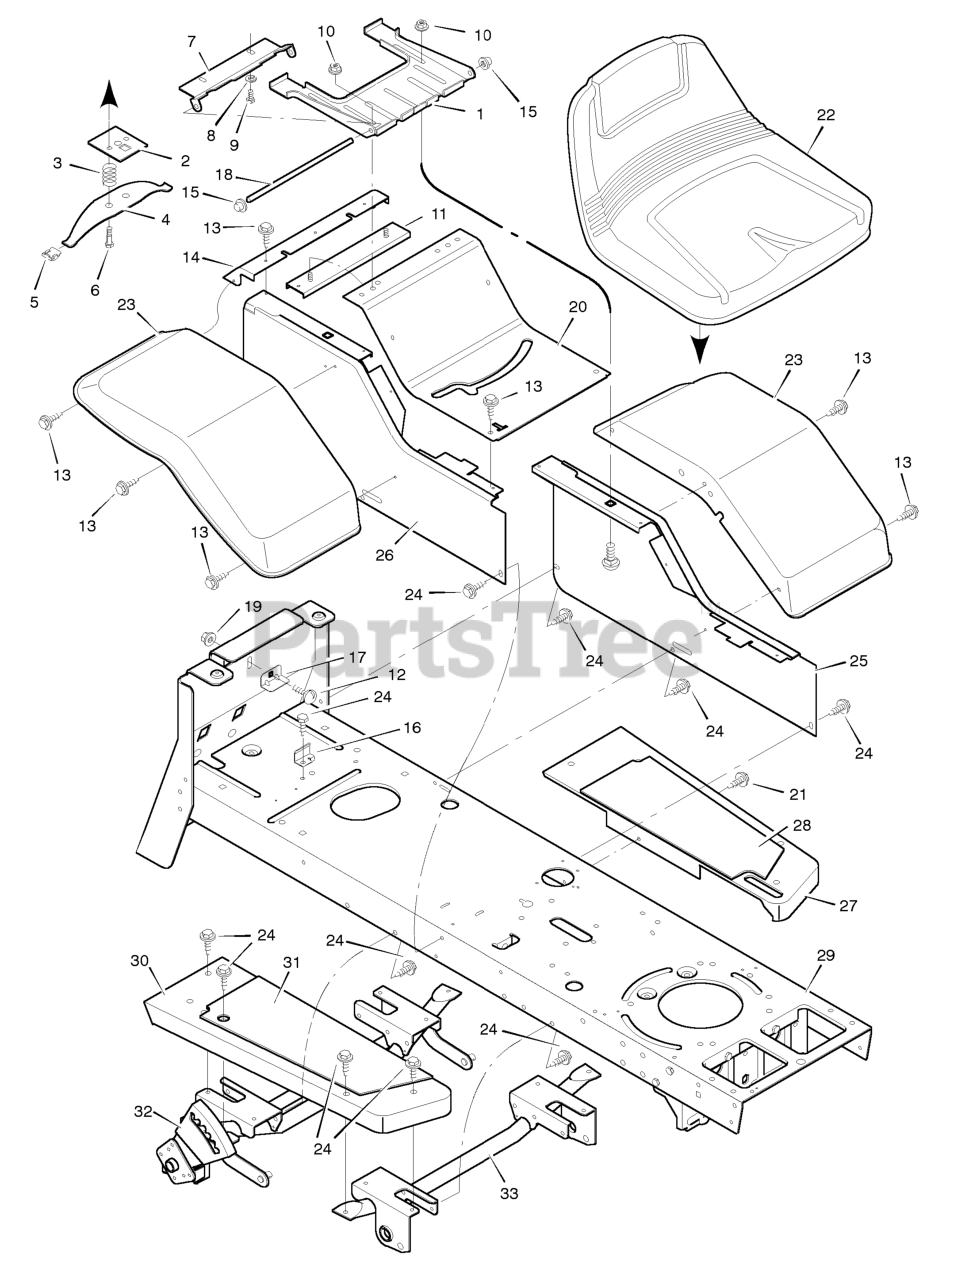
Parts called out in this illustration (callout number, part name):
1	Bracket, Seat
2	Plate Assembly, Switch
3	Spring, Compression
4	Spring, Seat
5	Glide, Spring
6	Bolt, Shoulder
7	Support, Seat
8	Lockwasher
9	Bolt, Hex
10	Locknut, Flange
11	Channel Assembly
12	Bolt, Carriage
14	Insert, Rear
15	Push On Cap
16	Clip, Battery
17	Clamp, Battery
18	Rod, Pivot
19	Locknut
20	Panel, Top
21	Fastener, Panel
25	Panel, Left
26	Panel, Right
27	Running Board, Left
28	Mat, Left
29	Frame Channel
30	Running Board, Right
31	Mat, Right
32	Lifter and Support Assembly
33	Support Assembly, Front
